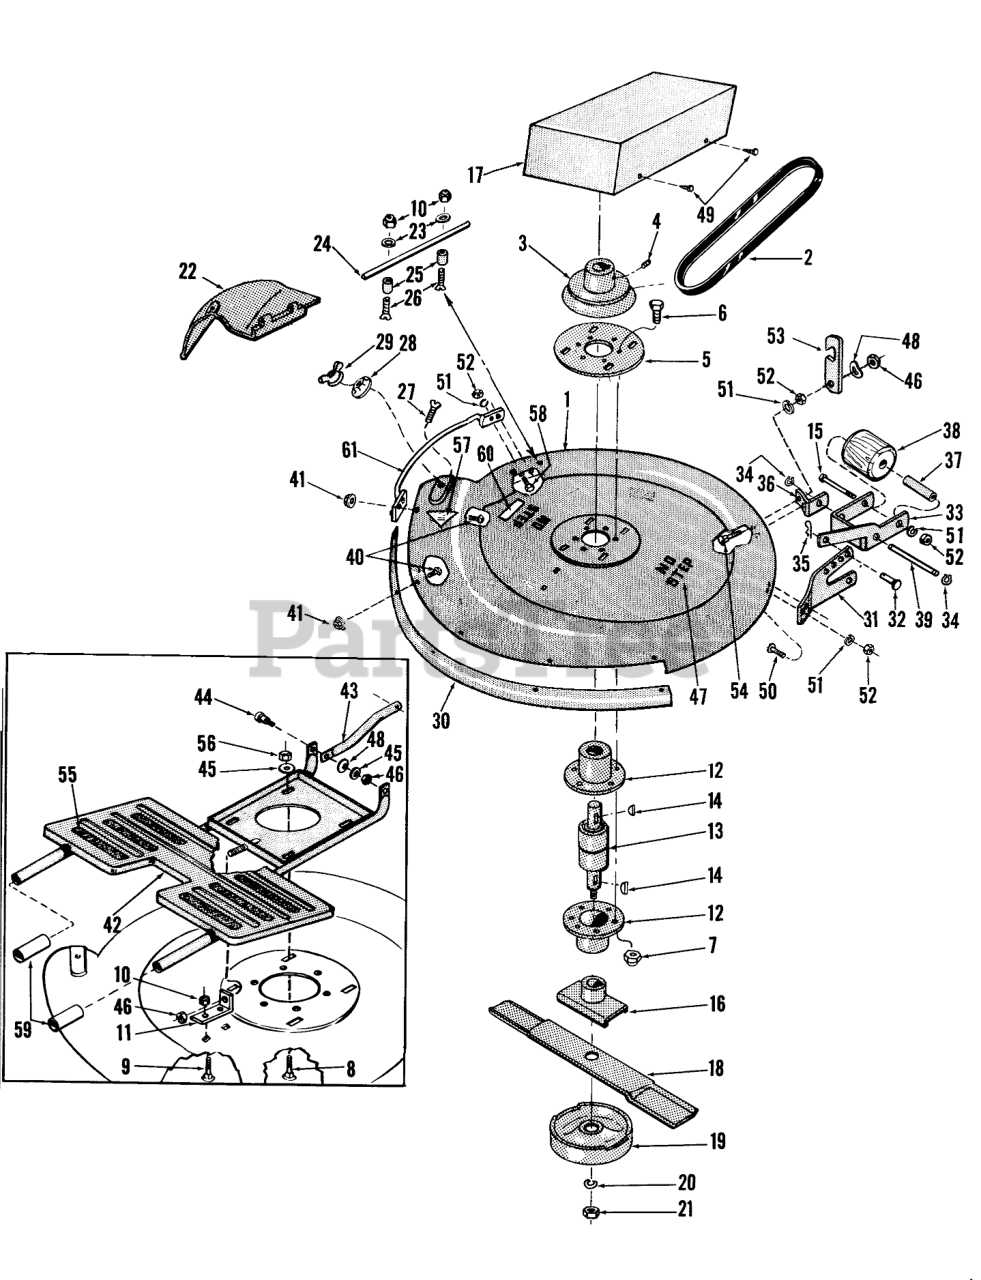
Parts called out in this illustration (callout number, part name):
1	Housing
2	V-Belt
3	Pulley
4	Setscrew
5	Plate
6	SCREW-HH
7	NUT-LOCK, NI
8	BOLT-CARR
9	SCREW-CARR
10	NUT-HEX
11	Bracket
12	BEARING HOUSING
13	Bearing Spindle
14	KEY-WOODRUFF
15	SCREW-HH
16	Retainer
17	Guard
18	Blade
20	WASHER-LOCK
21	Locknut
22	DEFLECTOR
23	WASHER-FLAT
24	Hinge Pin
25	Spacer
26	Screw
27	5/16-18X7/8 FLT HD MS
28	PAL NUT
29	Wing Nut
30	Cover
31	Pivot Bracket L.H.
33	Pivot, L.H.
34	E-RING
35	PIN-COTTER, HAIR
36	Support
37	Spacer
38	Roller
39	Pivot Pin
41	Nut
42	Cutter Support
43	Push Tube
44	SHOULDER BOLT
45	WASHER-FLAT
46	Nut
47	Decal
48	7/16 SPRING WASHER
49	SCREW-HWHTF
50	5/16-18X5/8 TRS HD MS
51	WASHER-LOCK
52	NUT-HEX
53	Transport Hook
54	Truss Head Machine Screw
55	Tread Pad
56	NUT-LOCK, NI
57	Decal
58	SCREW-PPH
59	Sleeve
60	Decal
